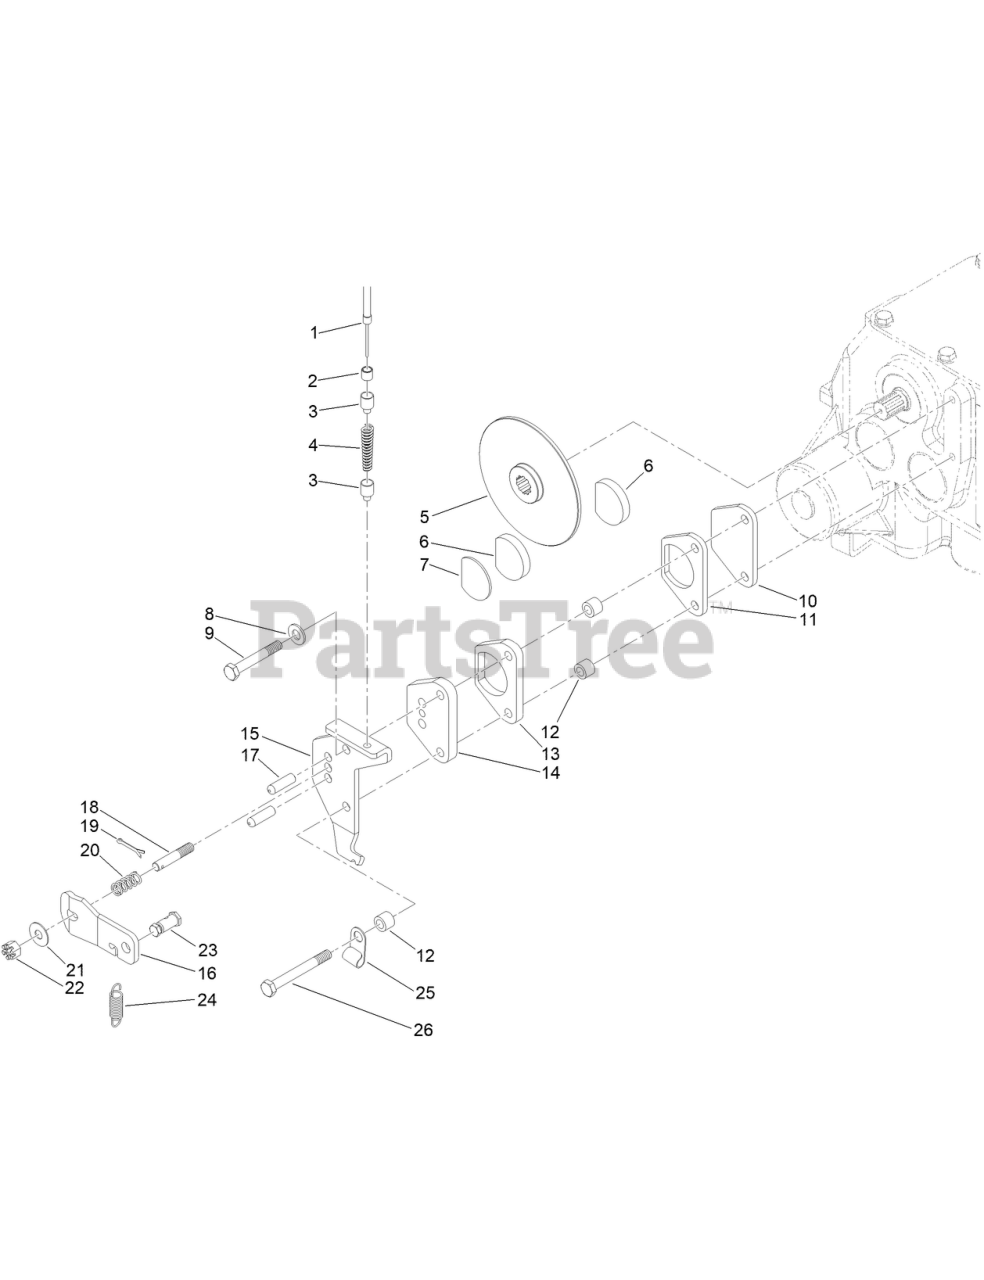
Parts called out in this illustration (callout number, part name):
1	CABLE, PARKING-BRAKE
2	CABLE-END, NIPPLE
3	BUSHING, PARKING BRAKE CABLE
4	SPRING-COMPRESSION
5	DISC, PARKING BRAKE
6	PAD, PARKING BRAKE
7	SHIM, PARKING BRAKE PAD
8	WASHER
10	SUPPORT, PAD
11	SUPPORT, PAD
12	SPACER
13	SUPPORT, PAD
14	SUPPORT, PAD
15	SUPPORT, PARKING BRAKE LEVER
16	LEVER, PARKING BRAKE
18	STUD, PARKING BRAKE
20	SPRING, PARKING BRAKE LEVER
23	CLAMP, PARKING BRAKE CABLE
24	SPRING, PARKING BRAKE CABLE
25	GROMMET
